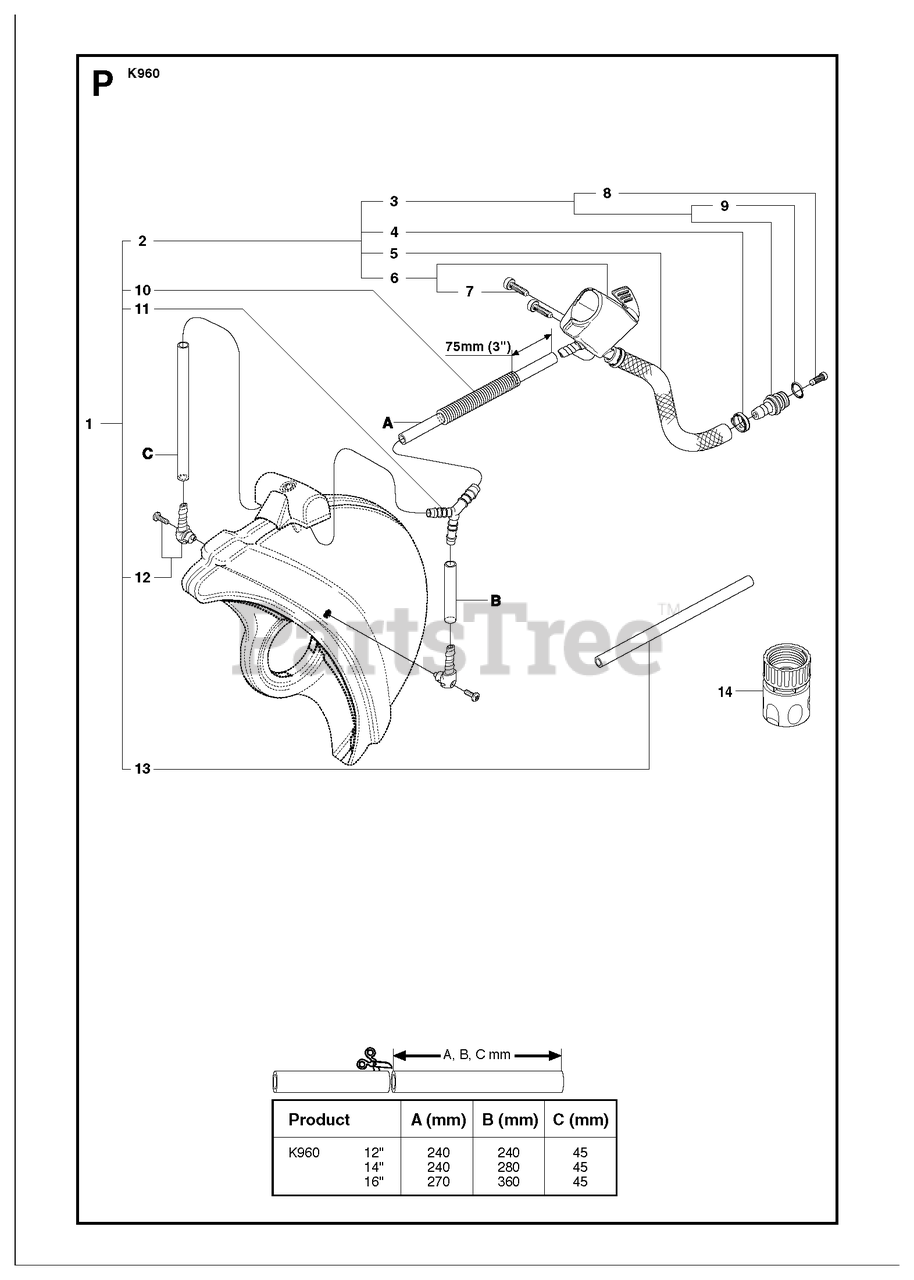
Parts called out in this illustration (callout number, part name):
1	HOSE KIT"12"", 14"". Incl. 2, 10 - 13"
1	HOSE KIT"16"". Incl. 2, 11 - 13"
2	HOSE ASSYIncl. 3 - 6
3	NIPPLEIncl. 7
4	HOSE CLAMP
5	HOSEL=230 mm
6	VALVE ASSYIncl. 7
7	SCREW ITXSCT
8	FILTERIncl. 9
9	O-RING
10	PROTECTIVE SPRING"16"" only"
13	HOSE800 mm
14	COUPLER
